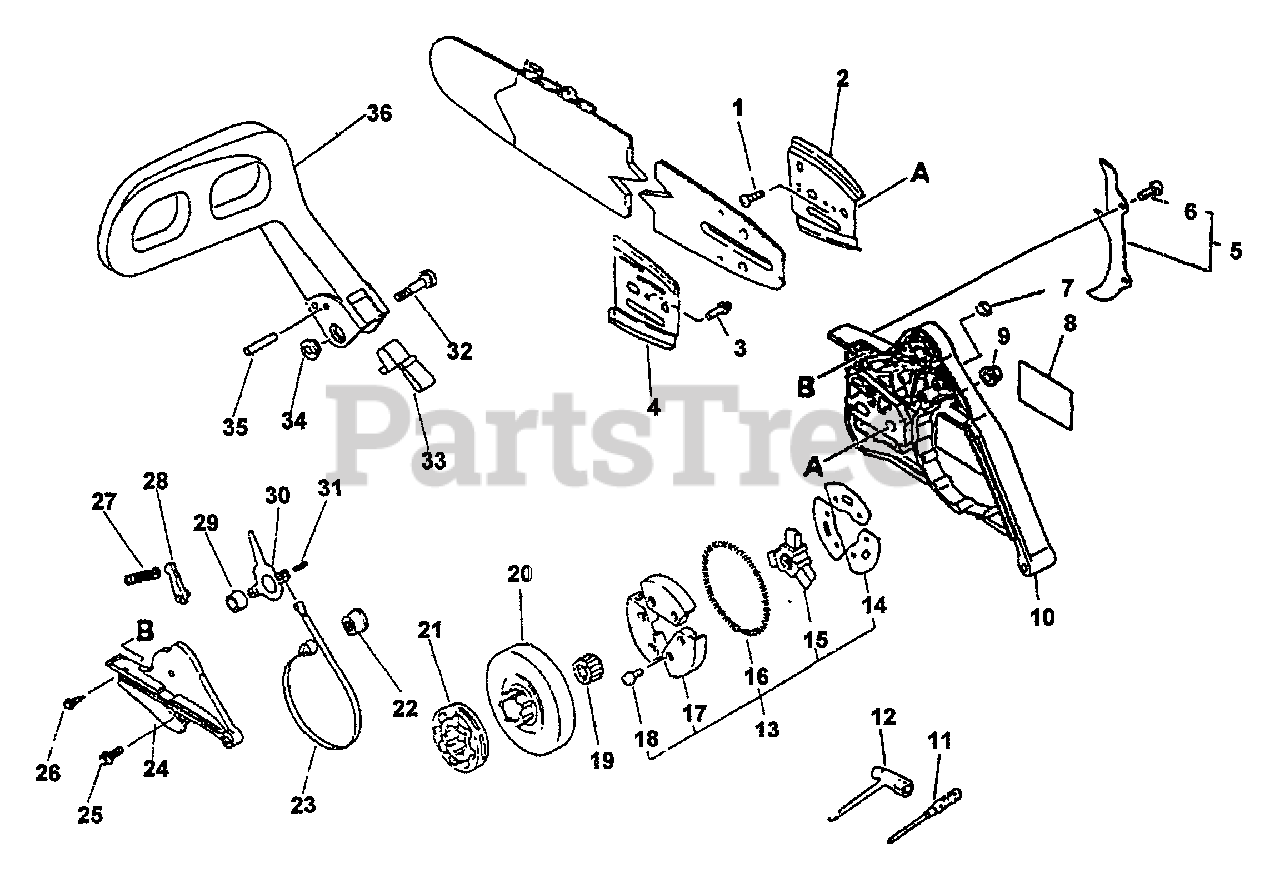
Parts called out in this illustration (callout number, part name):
1	SCREW 3×6
2	PLATE, GUIDE - OUTER
3	SCREW 4×8
4	PLATE, GUIDE - INNER
5	SPIKED BUMPER KIT
7	NUT 3 MM
8	LABEL, ECHO
9	NUT, FLANGE M8×1.25
10	GUARD, SPROCKET
11	SCREWDRIVER, PHILLIPS
12	T-WRENCH 13×19×180
13	CLUTCH ASSY
14	PLATE, CLUTCH
15	HUB, CLUTCH
16	SPRING, CLUTCH
17	CLUTCH SHOE SET
18	BOLT 4×6
19	BEARING, NEEDLE
20	DRUM, CLUTCH
21	SPROCKET, RIM 3/8"×7T
22	ADJUSTER, BRAKE
23	BAND, BRAKE
24	COVER, BRAKE
25	SCREW 3×18
26	SCREW 4×12
27	SPRING, BRAKE
28	STOPPER, BRAKE
29	SPACER 8×12×9
30	LEVER, BRAKE
31	PIN, SPRING - 4×8
32	MOUNTING KIT
33	SPRING, RETURN
35	PIN 3.5×26
36	LEVER, BRAKE
